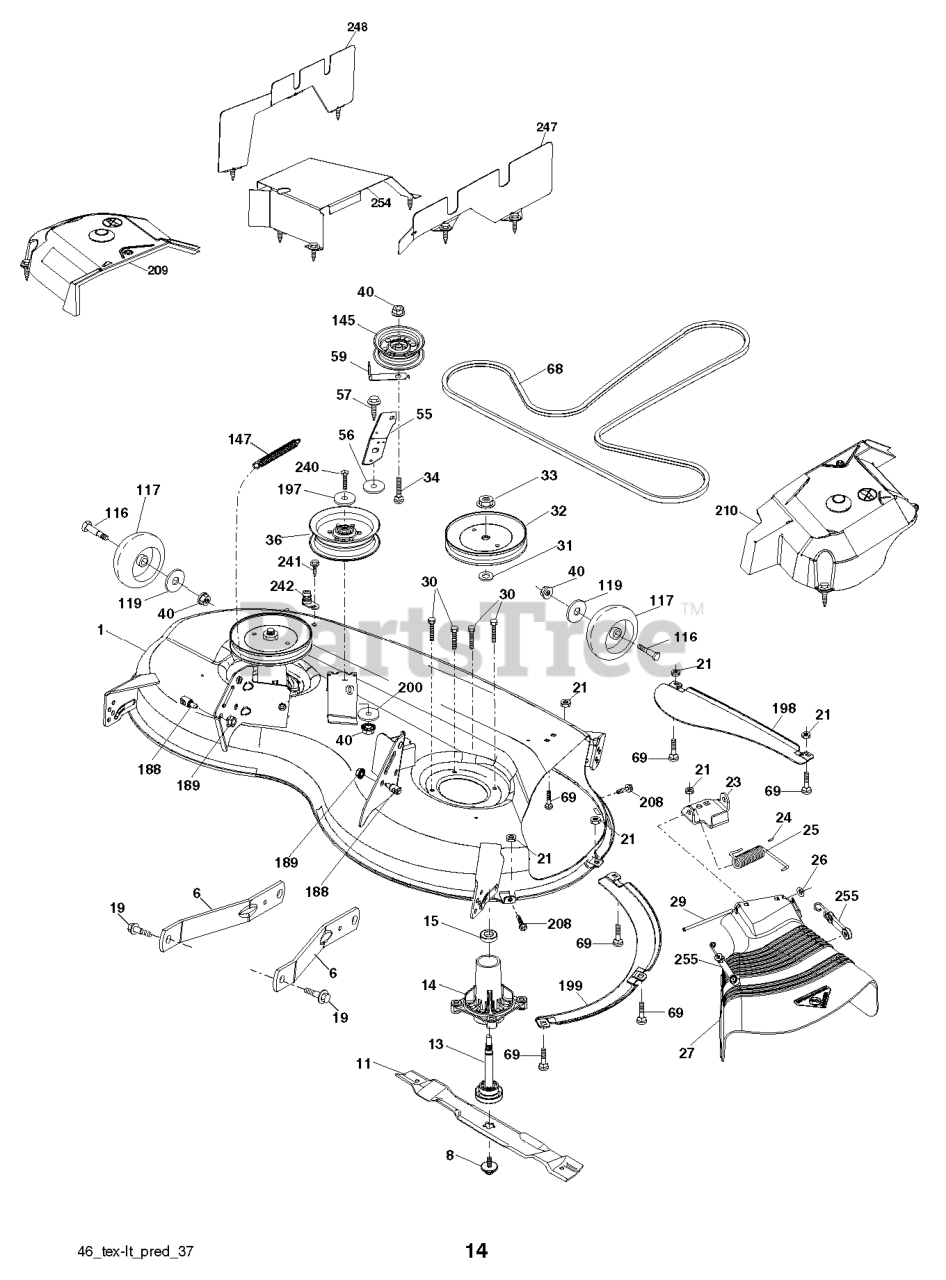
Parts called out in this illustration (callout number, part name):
6	ARM.SUSPENSION.MOWER.R
8	BOLT.WASHER.ASM.7/16-2
11	BLADE.MOWER.46".HI.LIFT
13	SHAFT.ASM.MDRL.N/GREASE.38
14	RP.HOUSING.MANDREL.4PT.
19	BOLT.SHOULDER
21	LOCKNUT
23	BRKT.DEFLECTOR.38"2005+
24	CAP-SLEEVE LT
25	SPRING.TORSION.DEFLECT
26	NUT PUSH M
27	SHIELD SUBASM DEFLECTOR 46 FRE
29	ROD.HINGE
30	SCREW, WASHER HEAD
31	WASHER.SPACER.MANDREL
32	PULLEY.MANDREL.5.438.PD
33	NUT.FLANGE.LOCK.TOP
34	BOLT.3/8-16X1.50
36	PULLEY.IDLER.2006
40	NUT LOCK FLG 3/8-16 UNC
56	SPACER.RETAINER
57	SCREW 3/8-16X1
59	GUARD, BELT
68	V-BELT
69	BOLT
116	BOLT.SHOULDER.3/8-16X3-5/8.
117	RP WHEEL. GUAGE RALLY
119	WASHER
145	PULLEY.IDLER.48"PRIMARY
147	SPRING.MOWER.DRIVE.ELECTRIC
188	STUD.FASTNER.W/ANTI-ROTATE
189	NUT LOCK HEX FLANGE 5/16-18
197	WASHER
198	BAFFLE CENTER FRONT
199	BAFFLE FRONT RH
200	WASHER.13/32 X 1 X 1/2.11GUARD
208	SCREW 3/8-16X1/2
209	COVER MANDREL LEFT
210	COVER MANDREL RIGHT
240	BOLT-HEX EAK
241	SCREW.TT.#10-32X.5.3/8.FLANGE
242	PORT.WASHOUT
247	SHIELD RIGHT
248	SHIELD LEFT
254	SHIELD ASSEMBLY 46 TEX REAR DE
255	ELASTIC STRAP KIT
